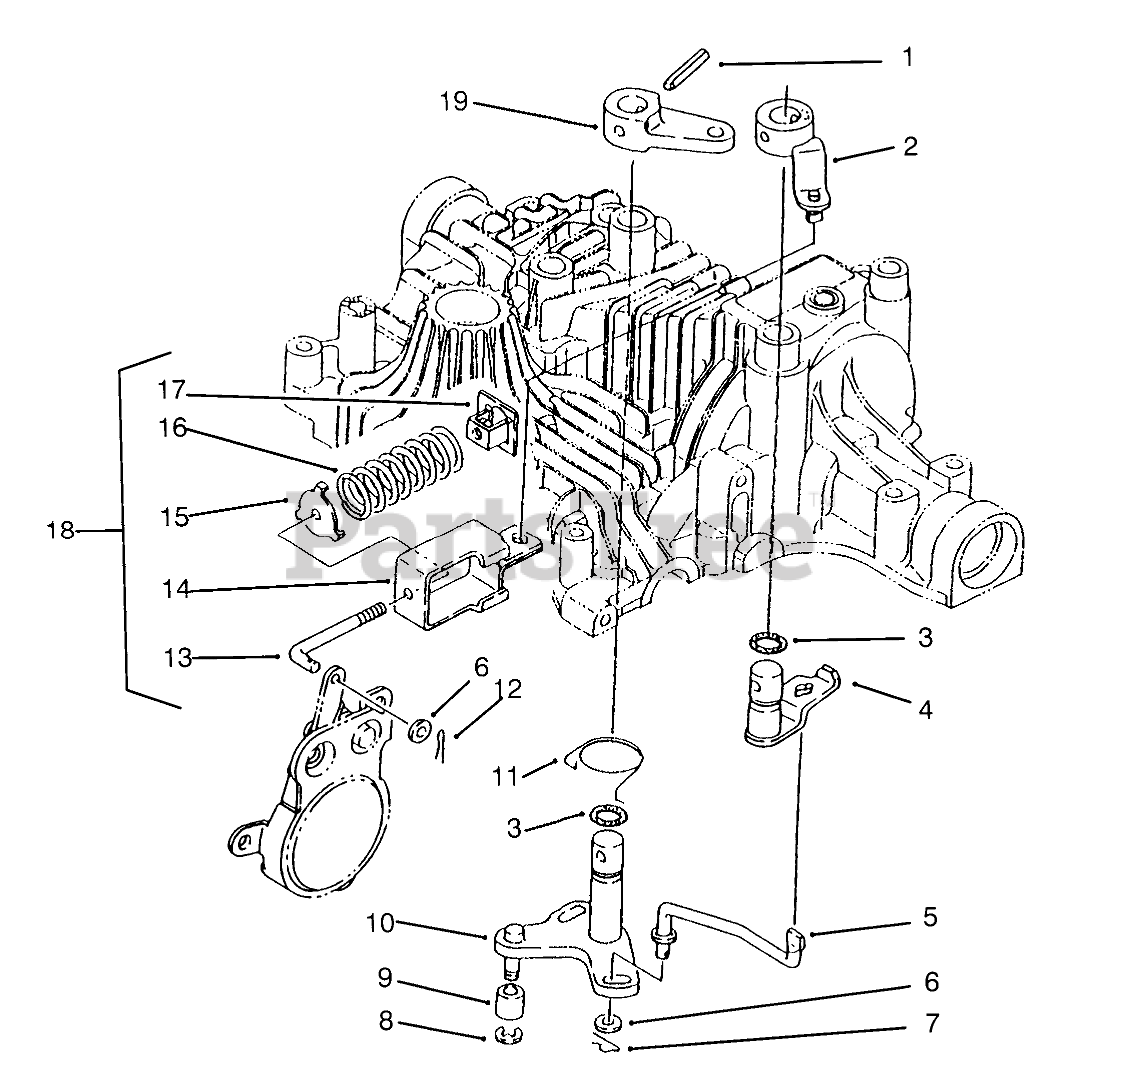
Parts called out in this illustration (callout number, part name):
1	Pin-Roll (Only On: 72043,72063,72103)
2	Arm-Brake B (Only On: 72043,72063,72103)
3	Packing (Only On: 72043,72063,72103)
4	Arm-Brake A (Only On: 72043,72063,72103)
5	Rod-Brake (Only On: 72043,72063,72103)
6	Washer (Only On: 72043,72063,72103)
7	Pin-Snap (Only On: 72043,72063,72103)
8	Ring (Only On: 72043,72063,72103)
9	Bushing (Only On: 72043,72063,72103)
10	Shaft-Brake (Only On: 72043,72063,72103)
11	Return-Brake (Only On: 72043,72063,72103)
12	Pin-Cotter (Only On: 72043,72063,72103)
13	Rod-Adjuster (Only On: 72043,72063,72103)
14	Holder-Spring (Only On: 72043,72063,72103)
15	Guide-Spring (Only On: 72043,72063,72103)
16	Spring (Only On: 72043,72063,72103)
17	Adjuster (Only On: 72043,72063,72103)
18	Rod ASM INCL 13-17 (Only On: 72043,72063,72103)
19	Arm-Brake (Only On: 72043,72063,72103)
